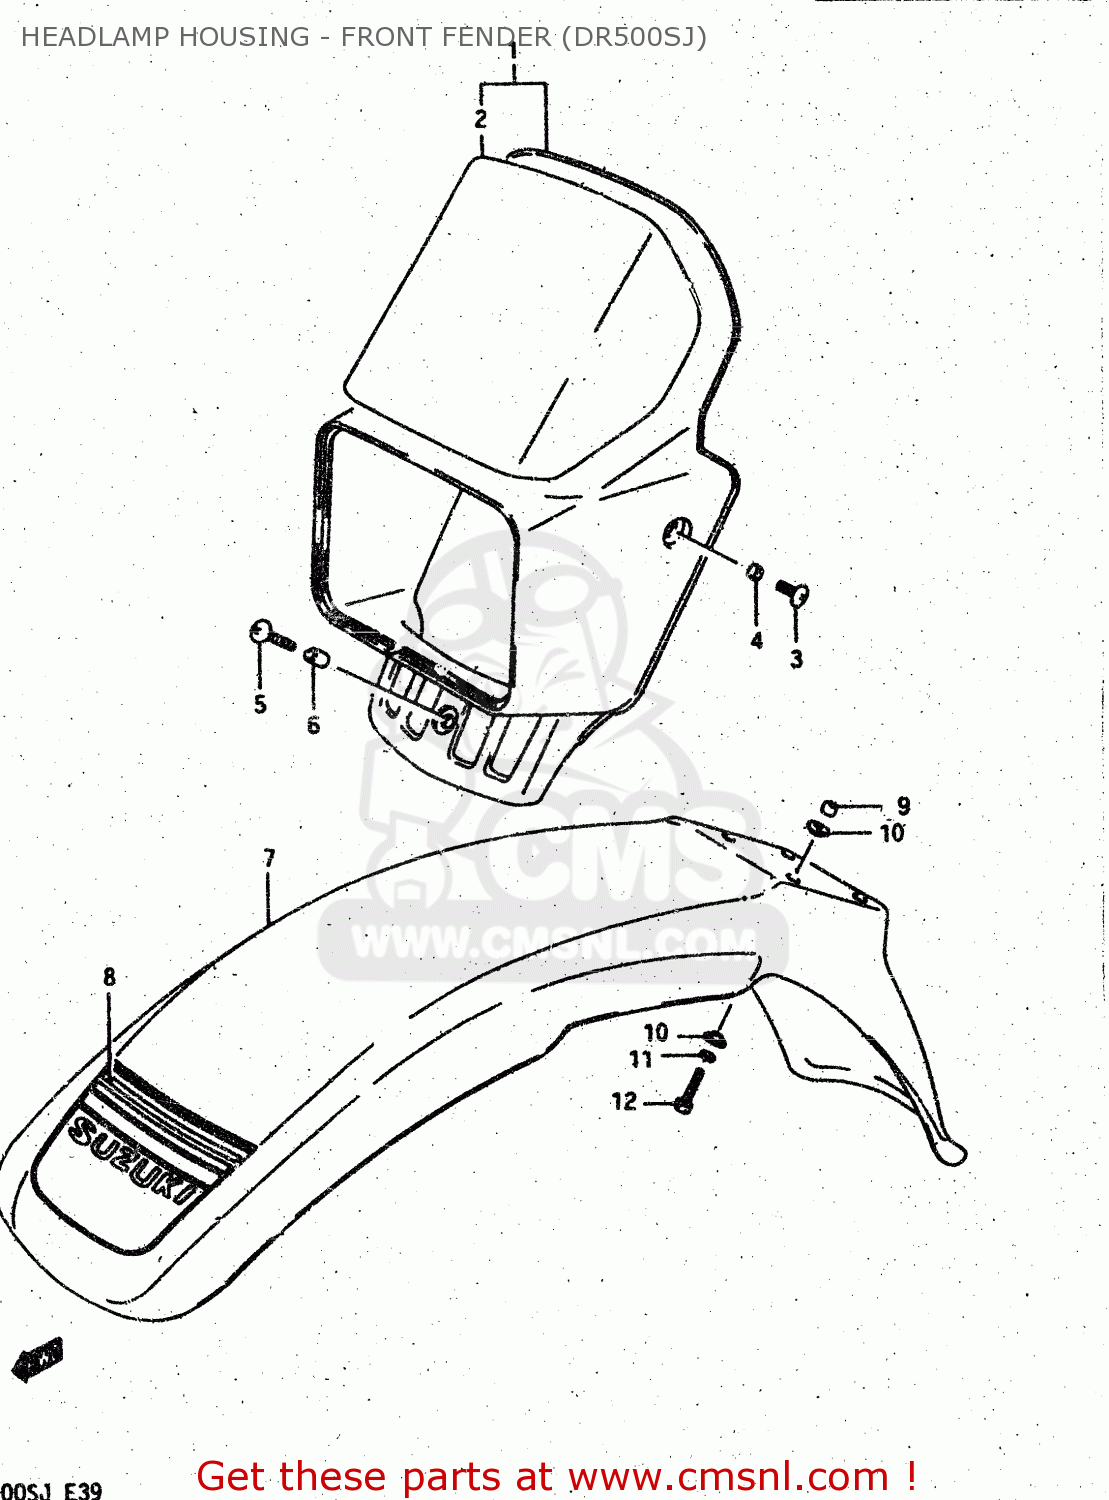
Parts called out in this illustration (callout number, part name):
1	COVER,HEADLAMP
2	TAPE SET (BLUE)
3	SCREW 6X12
4	SPACER (6.1X8X3.5)
5	SCREW, CENTER
6	SPACER (6.1X8X12)
7	FENDER, FRONT (BLUE)
8	TAPE,FR FENDER
9	SPACER(6.1X9X7.5)
10	WASHER
11	WASHER,LOCK
12	BOLT
